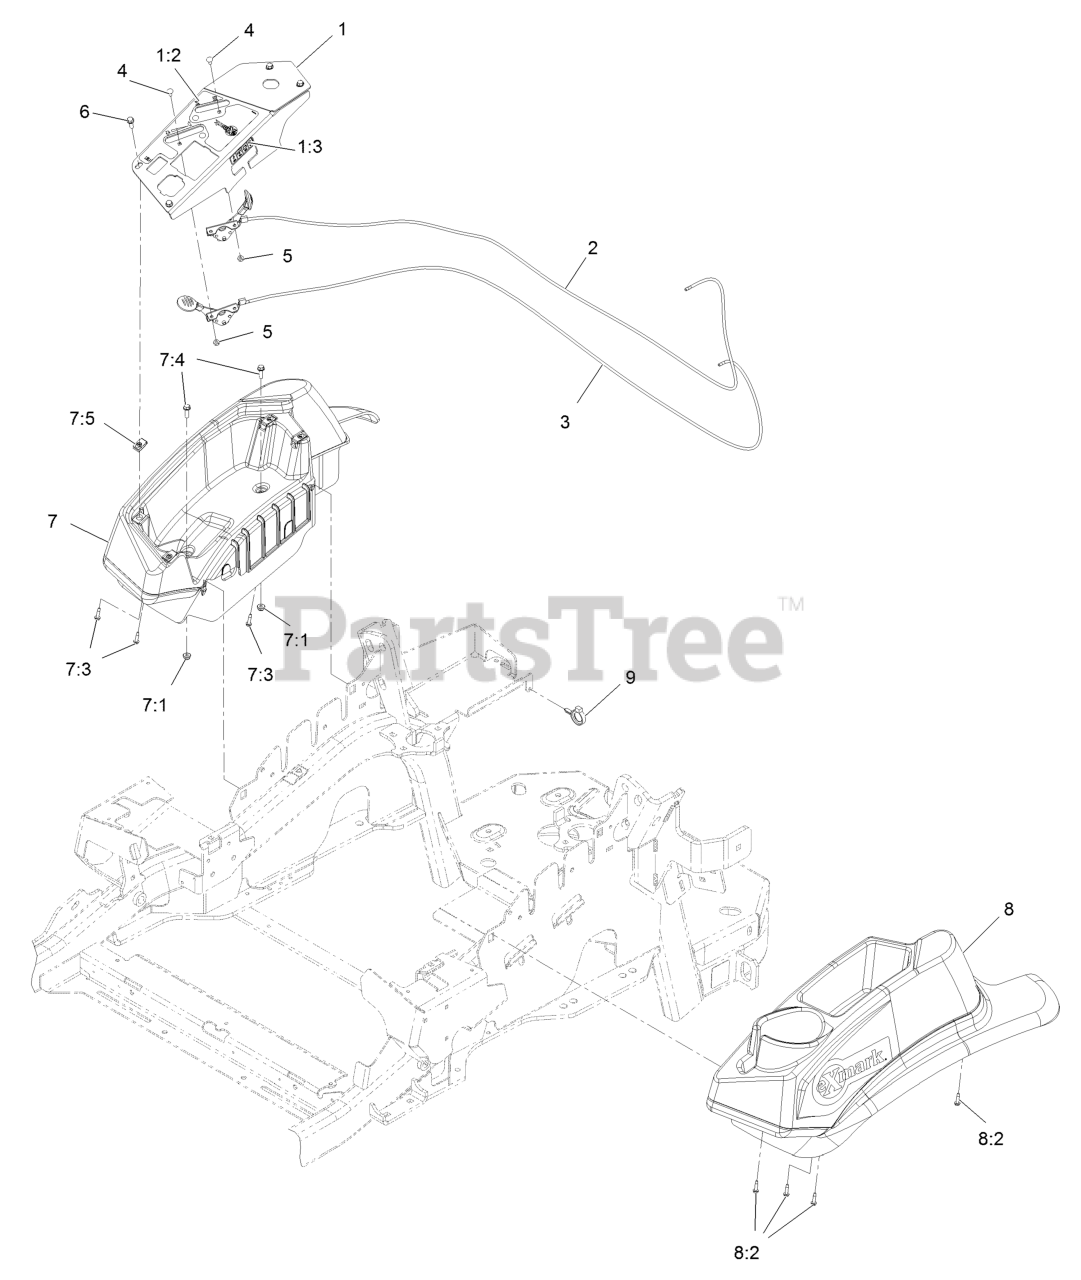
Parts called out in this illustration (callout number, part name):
1	CONSOLE,PANEL W/DECAL
1:2	DECAL-CONTROL PANEL NON-E
1:3	DECAL-FUSES
2	ASM, CHOKE CABLE
3	ASM,THROTTLE CABLE
4	BOLT-CARR
5	NUT-LOCK, NI
6	SCREW-HWH
7	CONSOLE,RH NARROW ASM
7:3	SCREW,THD FORM,HWH
7:4	SCREW-HWH
7:5	Nut-Retainer-Panel 1/4-20
8	CONSOLE.LH NARROW ASM
8:2	SCREW,THD FORM,HWH
9	CLAMP-HOSE
